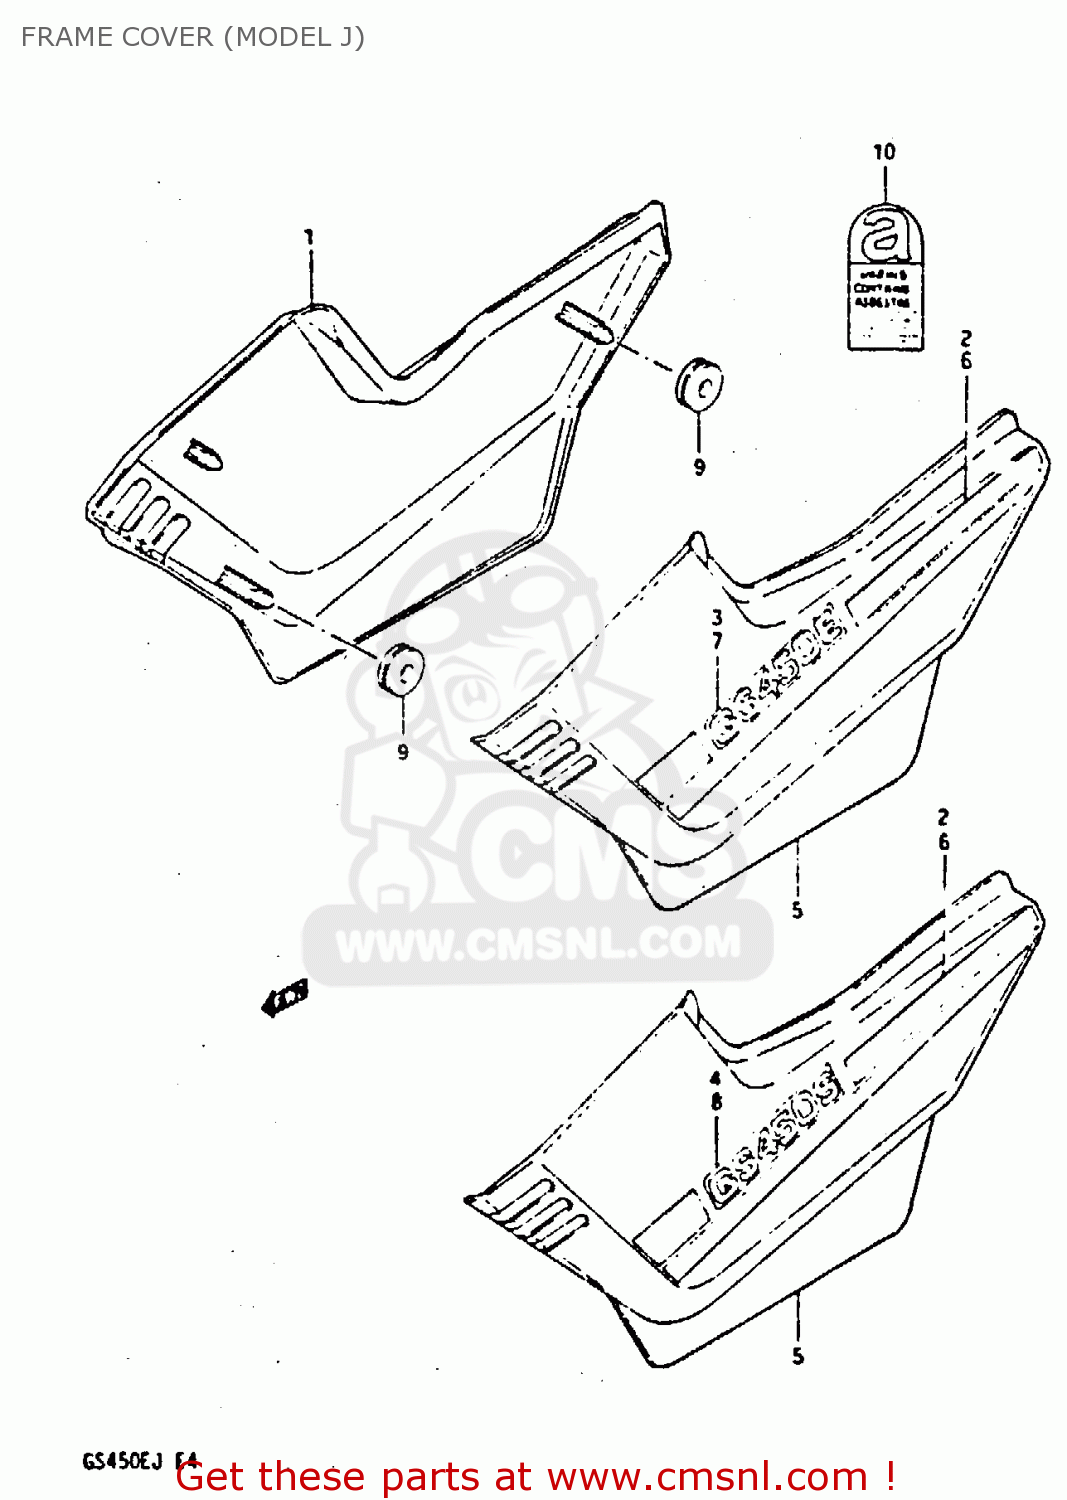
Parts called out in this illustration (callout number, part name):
1	COVER, FRAME RH (BLACK)
2	TAPE SET, FRAME COVER RH
3	EMBLEM
4	EMBLEM (WHITE)
5	COVER, FRAME LH (BLACK)
6	TAPE SET, FRAME COVER LH
7	EMBLEM
8	EMBLEM (WHITE)
9	CUSHION
10	LABEL,ASBESTOS WARNING
